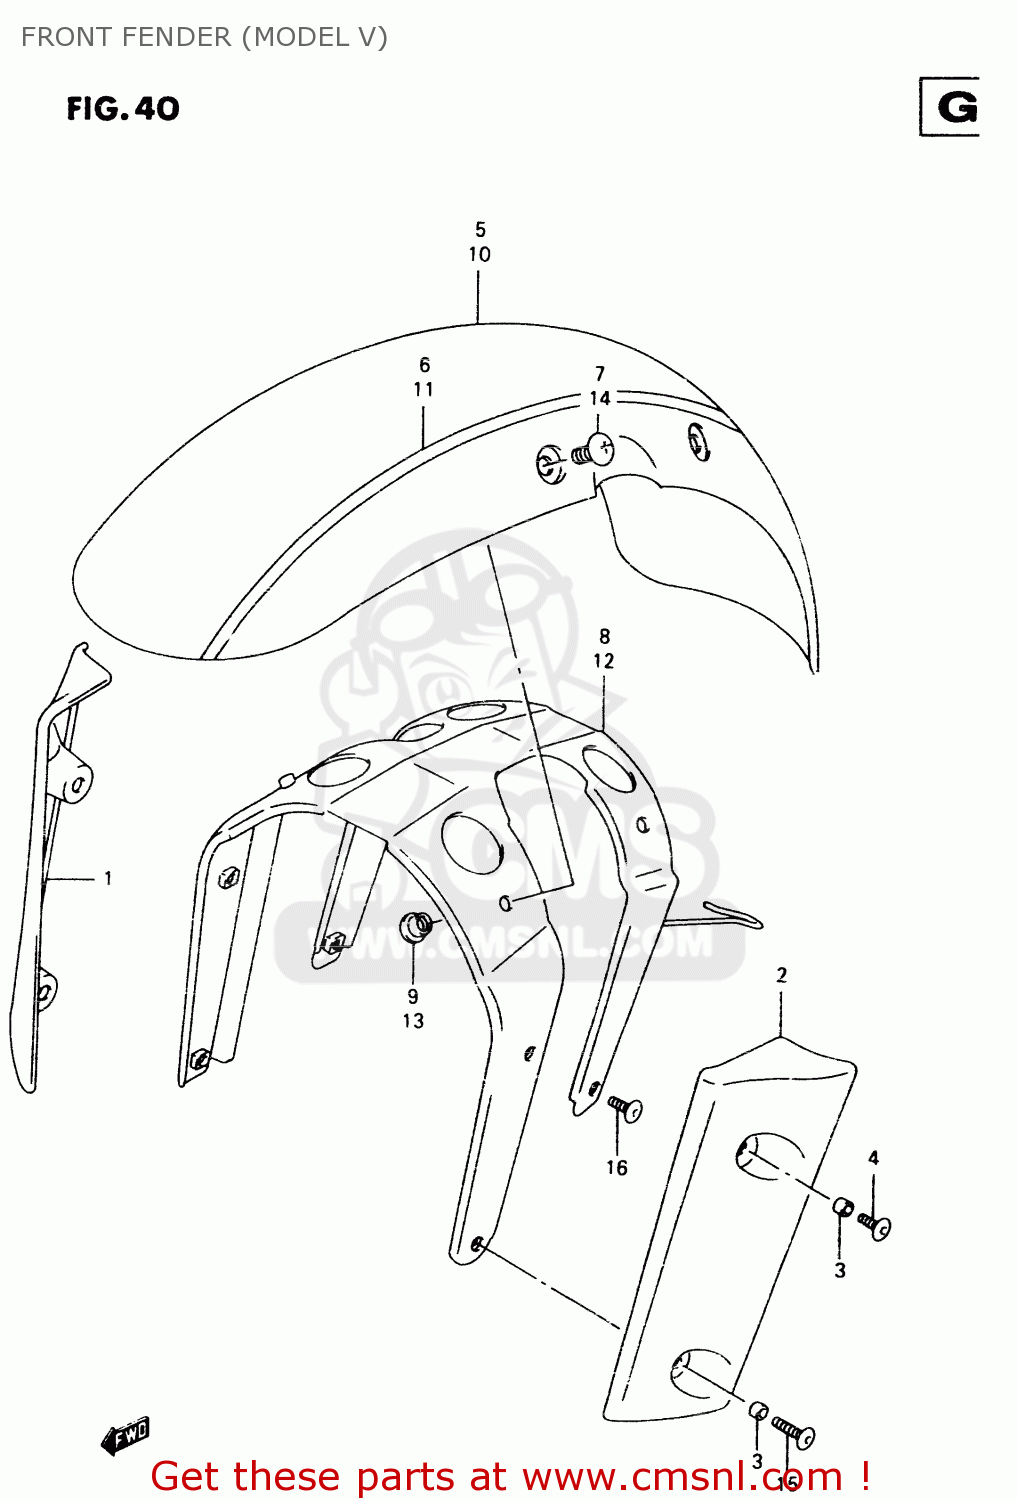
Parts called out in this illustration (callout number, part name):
1	COVER,FR FORK SIDE,R
2	COVER,FR FORK SIDE,L
3	SPACER(6.1X8X3.5)
4	SCREW(6X12)
5	FENDER,FRONT
6	TAPE SET, FRONT FENDER
7	SCREW(6X12)
8	BRACE,FR FENDER
9	NUT
10	FENDER, FRONT
11	TAPE SET, FRONT FENDER
12	BRACE,FR FENDER
13	NUT
14	SCREW(6X12)
15	SCREW(6X20)
16	SCREW(6X16)
